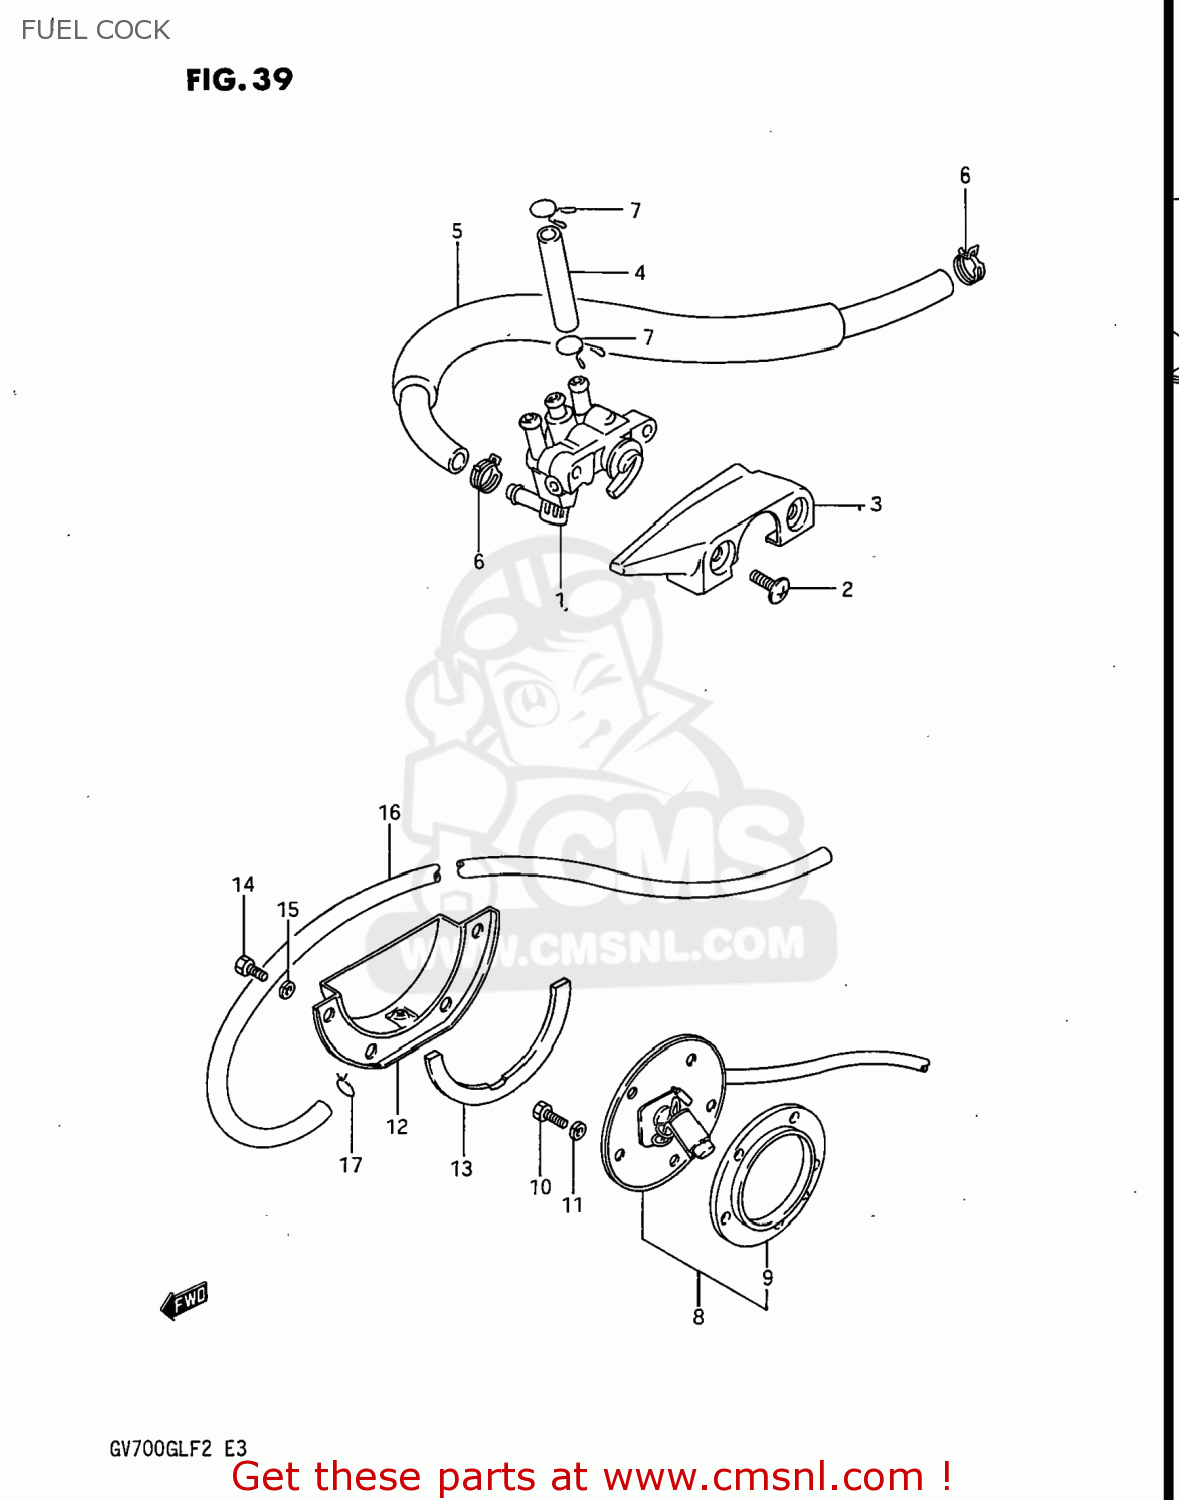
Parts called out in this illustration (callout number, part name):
1	COCK ASSEMBLY,FUEL
2	SCREW
3	COVER.FUEL COCK
4	HOSE
5	HOSE
6	CLAMP
7	CLIP
8	GAUGE ASSEMBLY,FUEL LEVEL
9	GASKET,FUEL LEVEL GAUGE (NAS)
10	BOLT 5X10
11	LOCK WASHER
12	PLATE,FUEL DRAIN
13	GASKET (NAS)
14	SCREW
15	LOCK WASHER
16	HOSE,FUEL
17	CLIP
